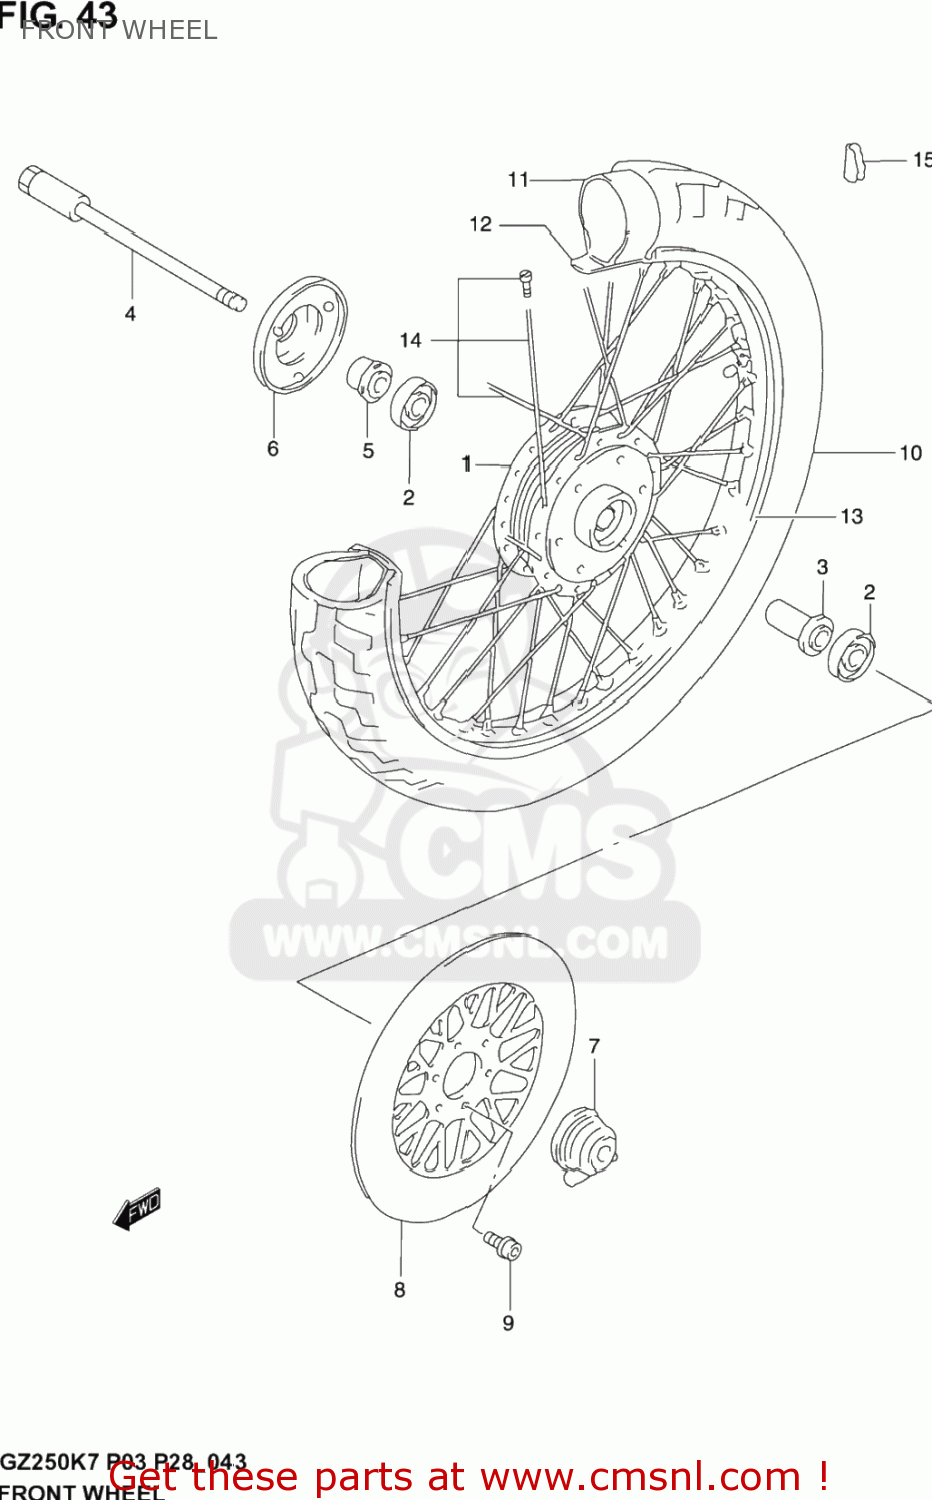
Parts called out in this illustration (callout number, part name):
1	HUB,FR WHEEL
2	BEARING
3	SPACER,FR HUB BEARING
4	AXLE FRONT
5	SPACER,FR HUB BEARING,R
6	COVER,FR HUB,R
7	BOX ASSY,SPEEDOMETER GEAR
8	DISC GZ125/K2-
9	BOLT(8X30)
10	TIRE, FRONT (110/90-16)
11	TUBE ASSY,WHL I
12	PROTECTOR, INNER TUBE
13	RIM,FR WHEEL(16XMT2.50)
14	SPOKE SET,FR WHEEL
15	BALANCER,WHEEL (B)
